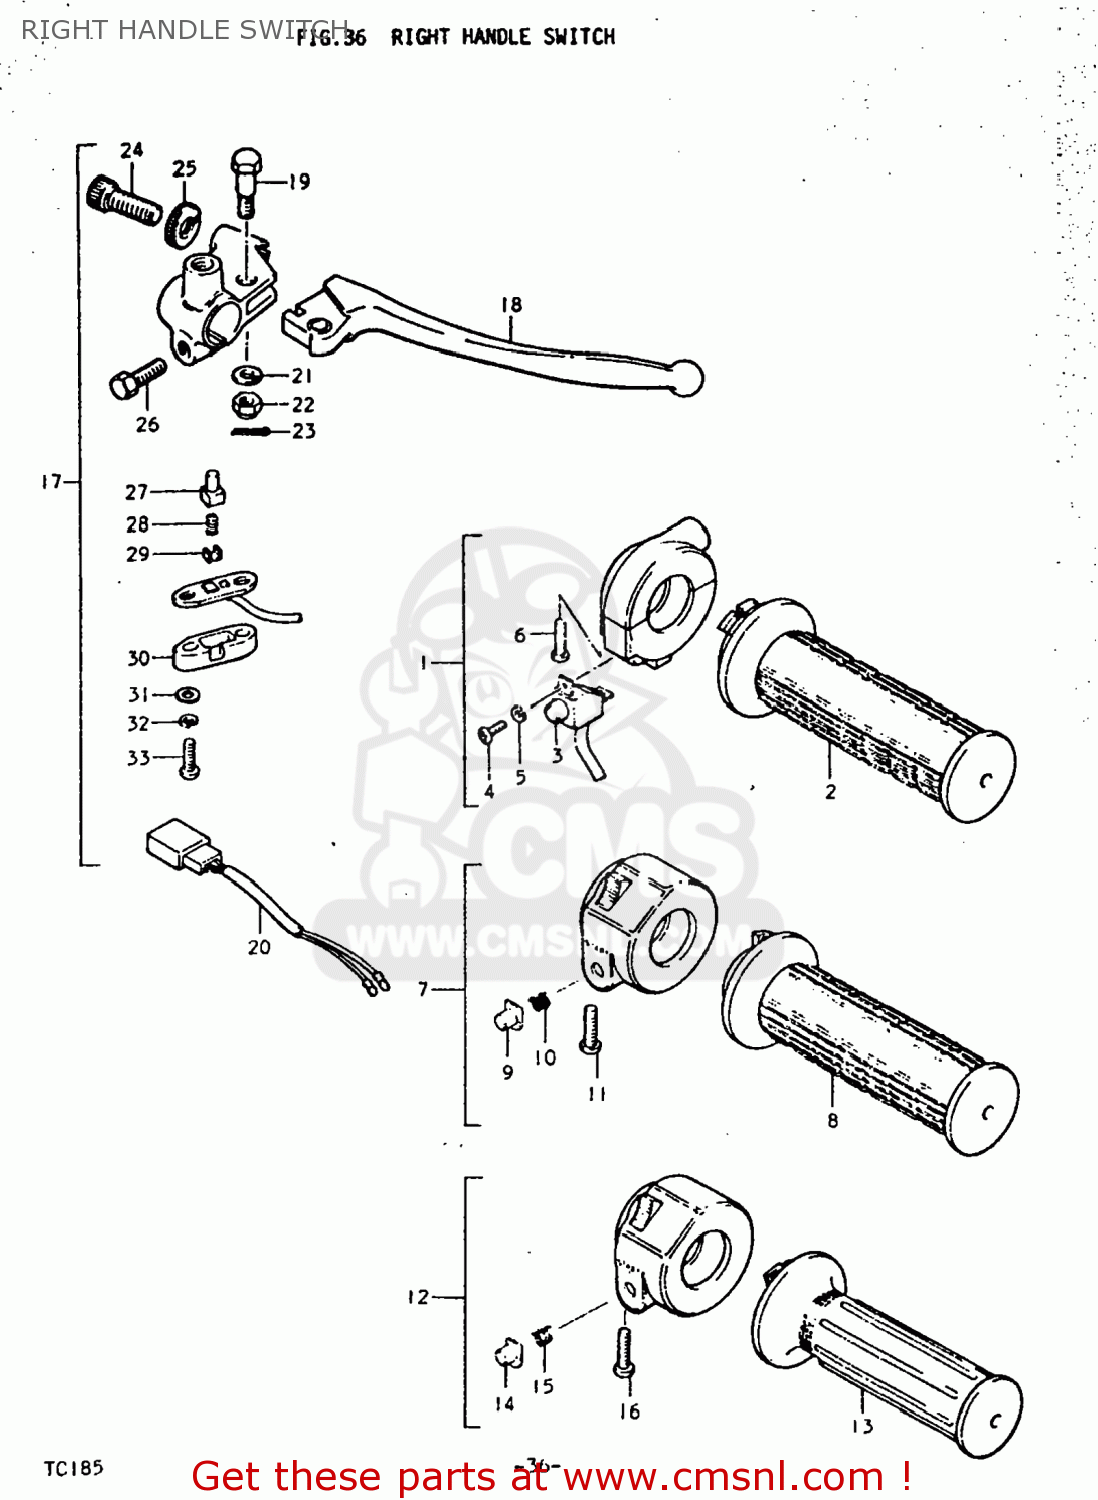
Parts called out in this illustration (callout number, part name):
1	CASE ASSEMBLY,THROTTLE
2	GRIP,THROTTLE
3	CASE ASSEMBLY,THROTTLE
4	SCREW
5	LOCK WASHER
6	SCREW
7	CASE ASSEMBLY,THROTTLE
8	GRIP,THROTTLE
9	BUTTON
10	SPRING
11	SCREW
12	CASE ASSEMBLY,THROTTLE
13	GRIP,THROTTLE
14	BUTTON
15	SPRING
16	CROSS HEAD SCREW
17	LEVER ASSEMBLY,BRAKE
18	LEVER ASSEMBLY,ADJUST
19	BOLT,LEVER
20	LEAD WIRE
21	LOCK WASHER
22	NUT,LEVER FITTNG
23	COTTER PIN
24	ADJUSTER,CABLE
25	NUT,CABLE ADJUSTER
26	BOLT
27	HOLDER
28	SPRING
29	PLATE
30	COVER,FR BK TERMINAL BASE
31	WASHER
32	LOCK WASHER
33	SCREW
